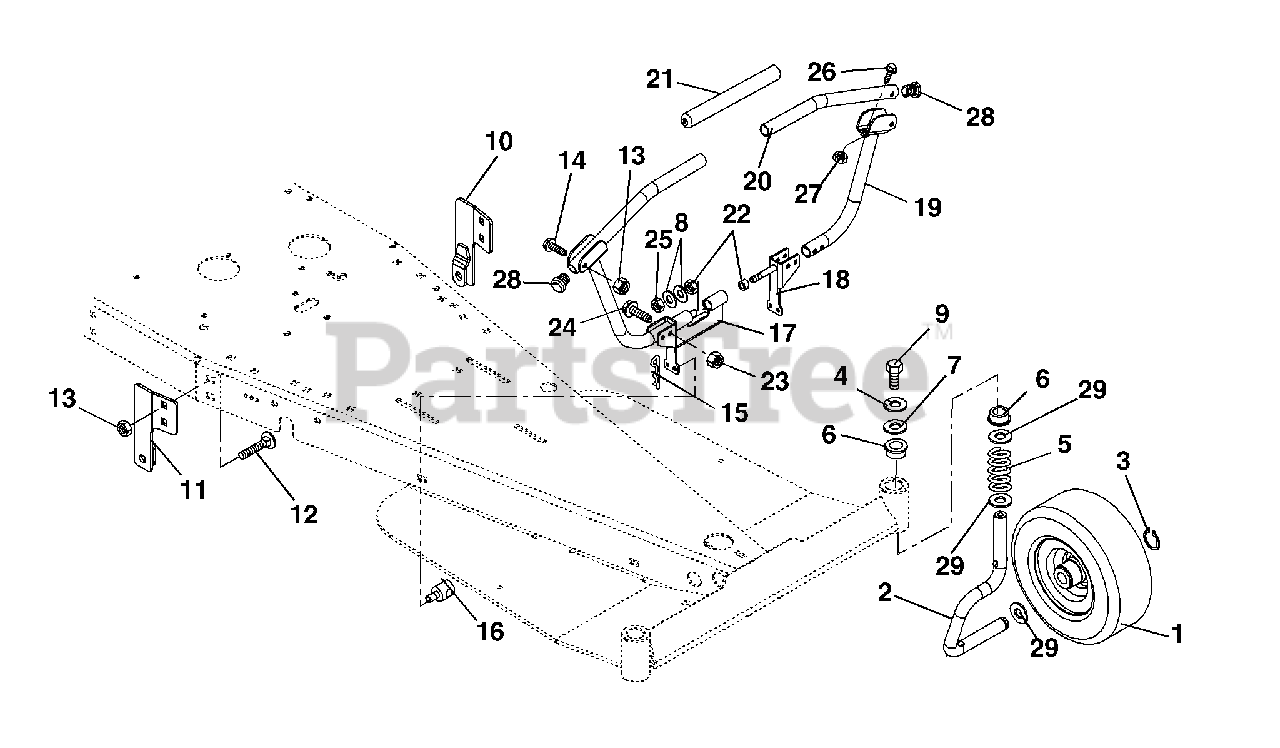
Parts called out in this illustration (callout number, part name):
1	WHL 9X3.50
2	SPINDLE, AXLE LH
3	RG-RTNG-EXT .750X.050
4	@WSHR-LK .31X.078 REG YWZC
5	SPRING, SUSPENSION
6	BUSHING-1"X.75"X1"
7	WSHR-FL-STL .406X1.375X.135 YZ
8	WSHR-HDND-STL-THR.515X.97X.062
9	@BLT-HEX .31-18X.75 GR5 YWZC
10	WLDM'T, DECK LINK LH
11	WLDM'T, DECK LINK RH
12	BLT-RDHDSQNK .38-16X1.00 G5BZ
13	NUT-LK-TOP-FLG .38-16 BLKZC
14	@BLT-HEX .38-16X1.75 GR5 YWZC
15	PIN-HAIR, ENDRIES #25 YWZC
16	TRUNNION, BRAKE .31-18 UNC
17	WLDM'T STEERING PIVOT
18	WLDM'T HANDLEBAR PIVOT
19	WLDM'T HANDLEBAR
20	HANDLE BAR (UPPER)
21	GRIP - HANDLEBAR
22	BSHG-FLG.500X.750X.750X1.000BR
23	NUT-LK-TOP-FLG .31-18 BLKZC
24	@BLT-HEX .31-18X1.50 GR5 YWZC
25	NUT-LK-JAM-NYL .50-20 GR2 YWZC
26	SCR-SKH .31-18X2.00 GR8
27	NUT- JAM .312-18 YWZC
28	CAPLUG, HANDLEBAR
29	WSHR-FL-STL .700X1.47X.134 YWZ
